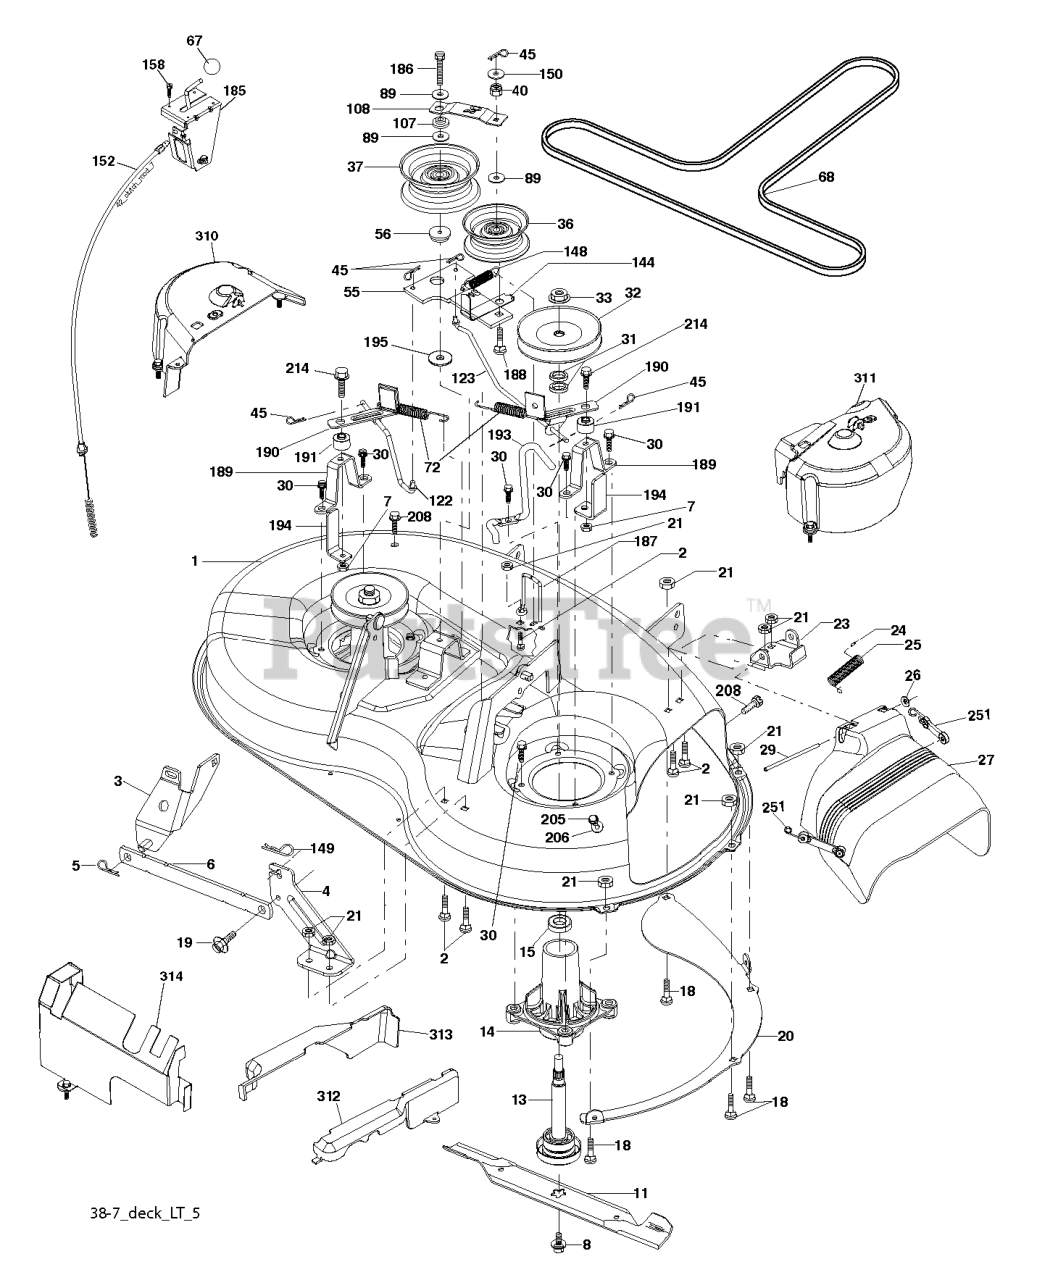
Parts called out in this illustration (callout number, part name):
1	CUTTING DECK
5	BLADE HOUSING ASSY
6	BEARING HOUSING
8	SPACING SLEEVE
10	BLADE HOUSING ASSY
11	BEARING HOUSING
13	SPACING SLEEVE
16	WASHER BRB 8.4X17
17	LOCKNUT M8
25	WASHER
27	BELT TENSIONER ASSY
27	BELT TENSIONER ASSY KIT
32	WASHER SHOULDER ASSY
32	WASHER
33	SCREW
34	LOCKNUT M8
36	BELT
37	BELT COVER
